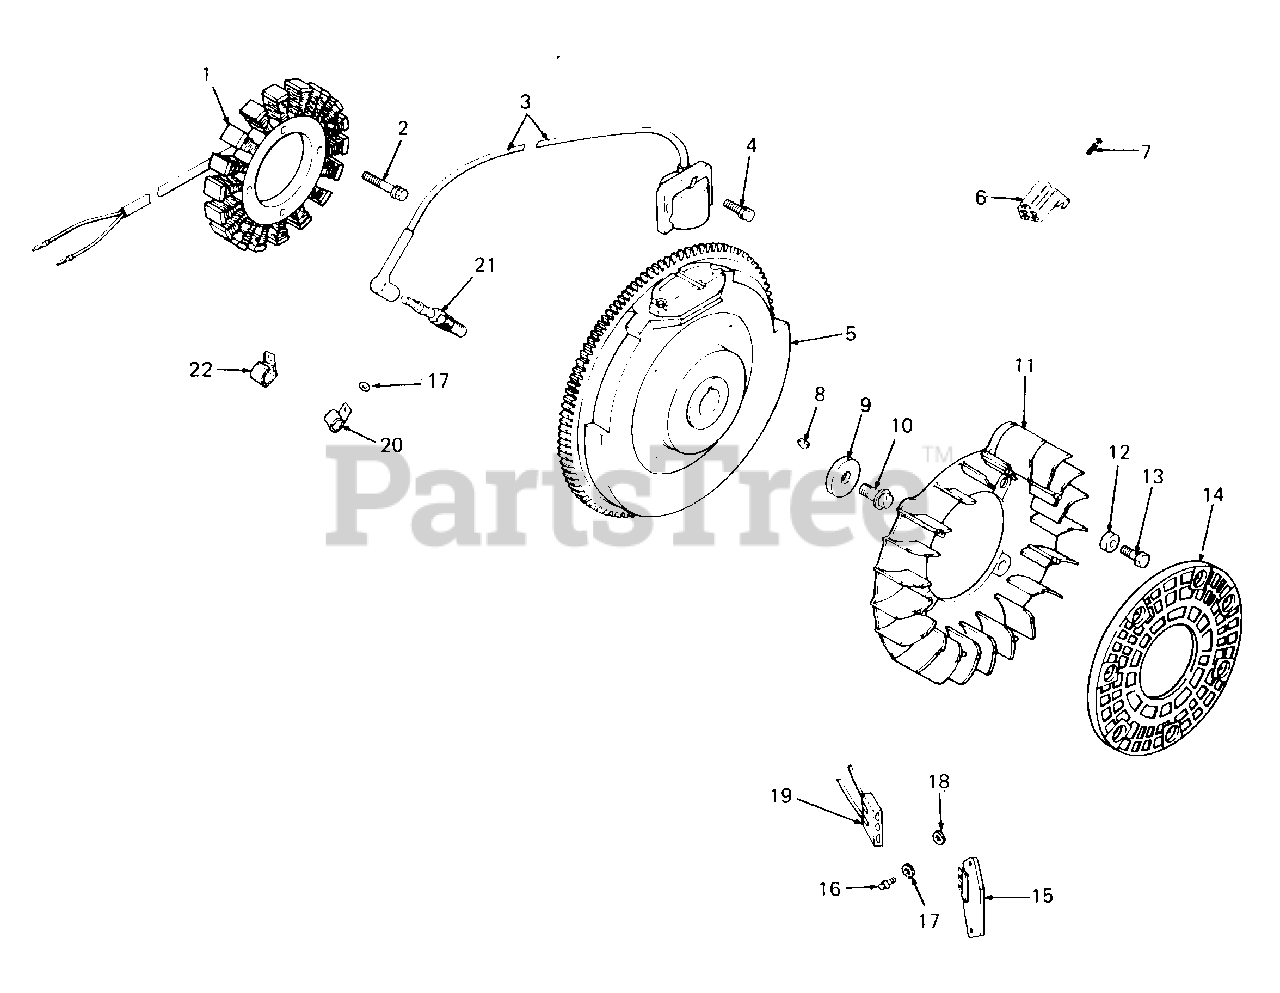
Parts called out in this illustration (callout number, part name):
1	Stator, 15 Amp
2	Screw, Stator Mtg, M5 X 0.8 X 25
3	Module, Ignition
4	Screw, Module, M5 X 0.8 X 20
5	Flywheel Assembly
7	Screw, Sltd Hex Hd, #10-16 X .50
9	Washer, Flywheel Mtg Screw
10	Screw, Flywheel Mtg, M10 X 1.5 X 45.8
11	Fan
12	Spacer, Fan
13	Screw, M6 X 1.0 X 16
14	Screen, Grass
15	Regulator-Rectifier
16	Screw, #11-16 X .78
17	Washer, Plain, 1/4
18	Washer, Plain
19	Connector, Regulator-Rectifier
20	Clip, Cable
21	Spark Plug
